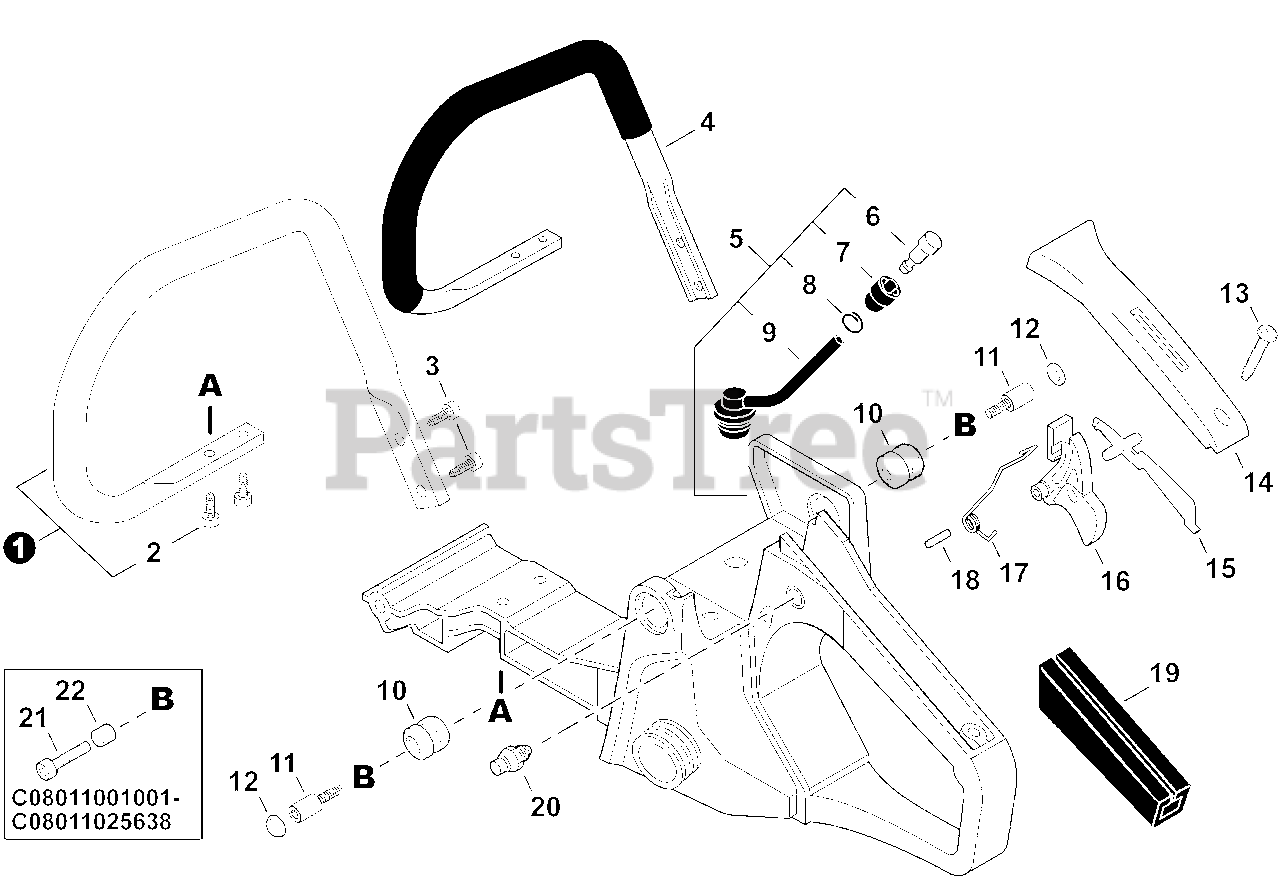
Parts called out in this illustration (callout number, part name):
1	HANDLE SET, FRONT - NYLON
2	SCREW TAPPING 5×20
3	SCREW TAPPING 5×20
4	HANDLE, FRONT - ALUMINUM
5	HANDLE ASSY, REAR
6	VENT ASSY
7	HOLDER, VENT
8	CLIP 6.5 MM
9	PIPE, VENT 3×6×65
10	CUSHION 4
11	BOLT 4×10×13.5
12	CAP, CUSHION
13	SCREW 4×14
14	COVER, HANDLE
15	LOCKOUT, THROTTLE
16	TRIGGER, THROTTLE
17	SPRING, TORSION
18	PIN, SPRING 4×30
19	GRIP, HANDLE
20	LOCK, THROTTLE TRIGGER
21	BOLT 4×22
22	COLLAR 4
